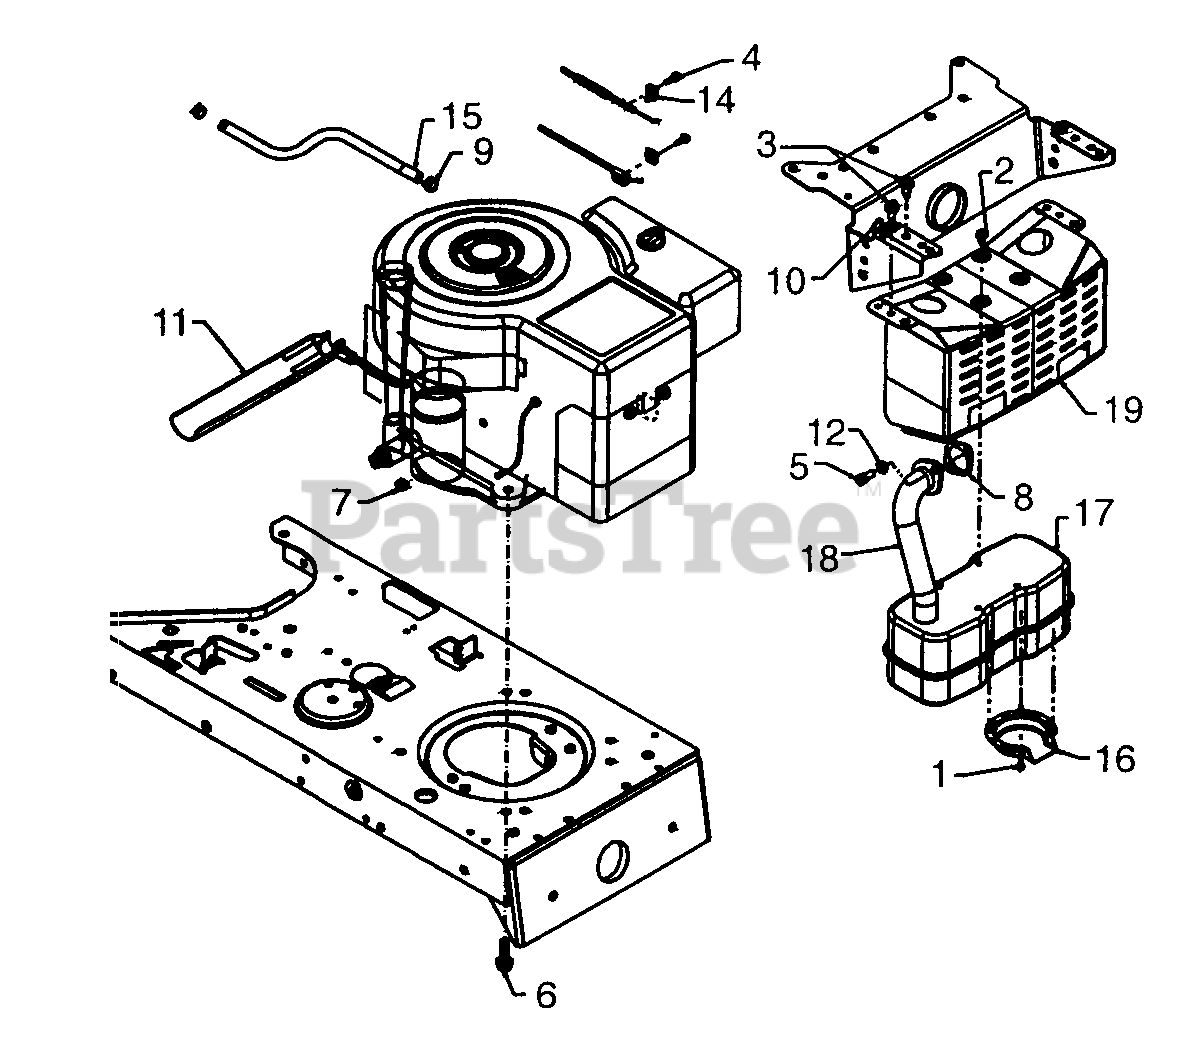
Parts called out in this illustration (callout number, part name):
1	Hex Tap Scr. #8-32 x .38" Lg.
2	Hex TT Tap Scr. 1 /4-20 x .5" Lg.
3	Hex TT Tap Scr. 5/16-18 x .62"
4	Hex Wash. Scr. #10-32 x .62"
5	Socket Head Scr. 5/16-18 x .62"
6	Hex TT Tap Scr. 3/8-16 x 1.25"
7	Hex Sems Scr. 1/4-20 Thd.
8	Gasket
9	Hose Clamp
10	Clamp
11	Oil Drain Sleeve
12	Lock Washer 5/16" I.D.
14	Casing Clamp
15	Fuel Line 12" Lg.
16	Muffler Deflector
17	Muffler
18	Exhaust Pipe
19	Muffler Brkt.
